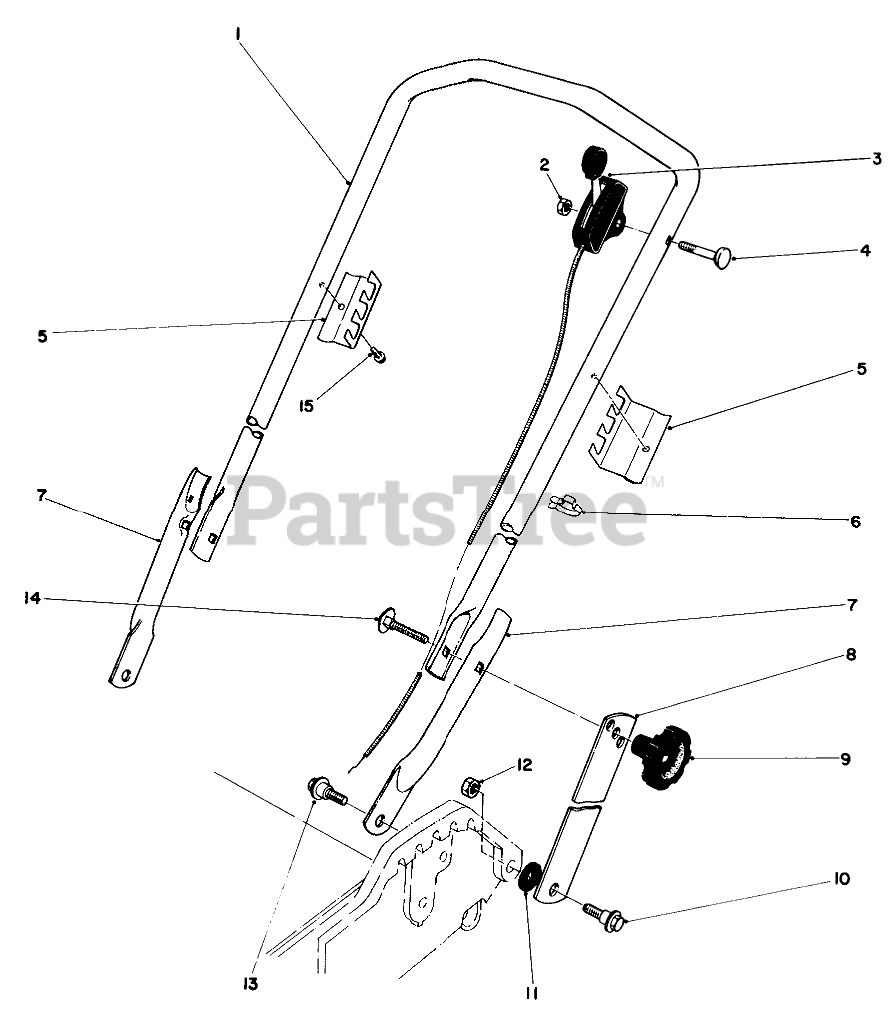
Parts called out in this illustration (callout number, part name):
1	Handle-Upper
2	NUT-LOCK, NI
3	SERVICE THROTTLE CONTRO
4	SCREW-HANDLE
5	Bag Support
6	BOWDEN CLIP
7	Hand-Lower
8	Handle Latch
10	SCREW-SHOULDER
11	SPACER
12	NUT-LOCK, NI
13	SCREW-SHOULDER
14	5/16-18 X 2 HNDLE SCREW
15	SCREW-HWHTF
